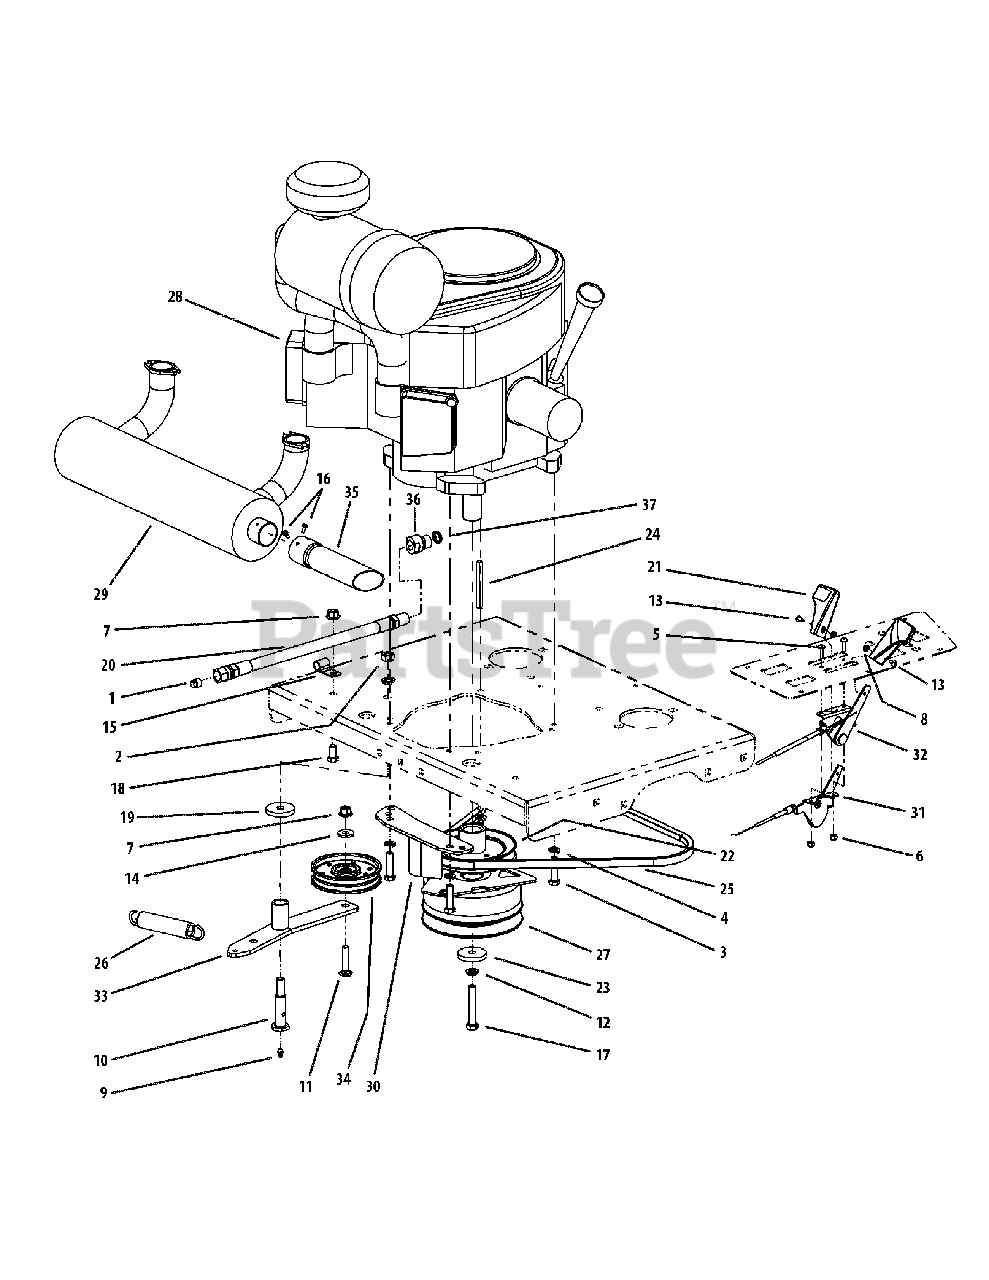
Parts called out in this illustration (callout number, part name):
1	Pipe Plug, 3/8 NPT
2	Hex Nut, 7/16-14
3	Hex Head Cap Screw, 3/8-16 x 1.50
4	Washer lock 3/8 zinc
5	Machine Screw, 10-32 x 5/8
6	Lock Nut, Nylon Insert, 10-32
7	Flange Lock, Hex Nut, 3/8-16
8	Nut Washer, W/Star, 8-32
9	Grease Fitting, 1/4-28 x 3/16
10	Shoulder Screw, 7/16-14
11	Hex Carriage Screw, 3/8-16, 1.75
12	Lock Washer, 7/16
13	Machine Screw, 8-32, .375
14	Flat Washer, .406 ID, 1.0 OD, .105
15	Clip, Heat Shield Cable
16	Screw, #10-16 x .500
17	Capscrew, 7/16-20 x 2.50
18	Hex Cap Screw, 3/8-16, .750
19	Flat Washer, 7/16 ID x 1.75 OD x .25
20	Oil Drain Hose
21	Control Throttle Knob
22	Pump Drive Pulley
23	Flat Washer, 7/16 ID x 1.75 OD x .25
24	Key, 1/4 x 1/4 x 3
25	Belt, 51.2 Lg
26	Extension Spring, .98 OD x 5.00
27	Clutch Brake, 1.125 ID
28	Engine, 37HP Kawasaki
29	Muffler, Kawasaki
30	Retainer Clutch Assembly
31	Throttle, Control Cable
32	Choke, Control Cable
33	Engine Idler Arm includes:
33	Bearing
34	Flat Pulley with Flanges
35	Muffler Accessory Exhaust Tube
36	Oil Drain Adaptor
